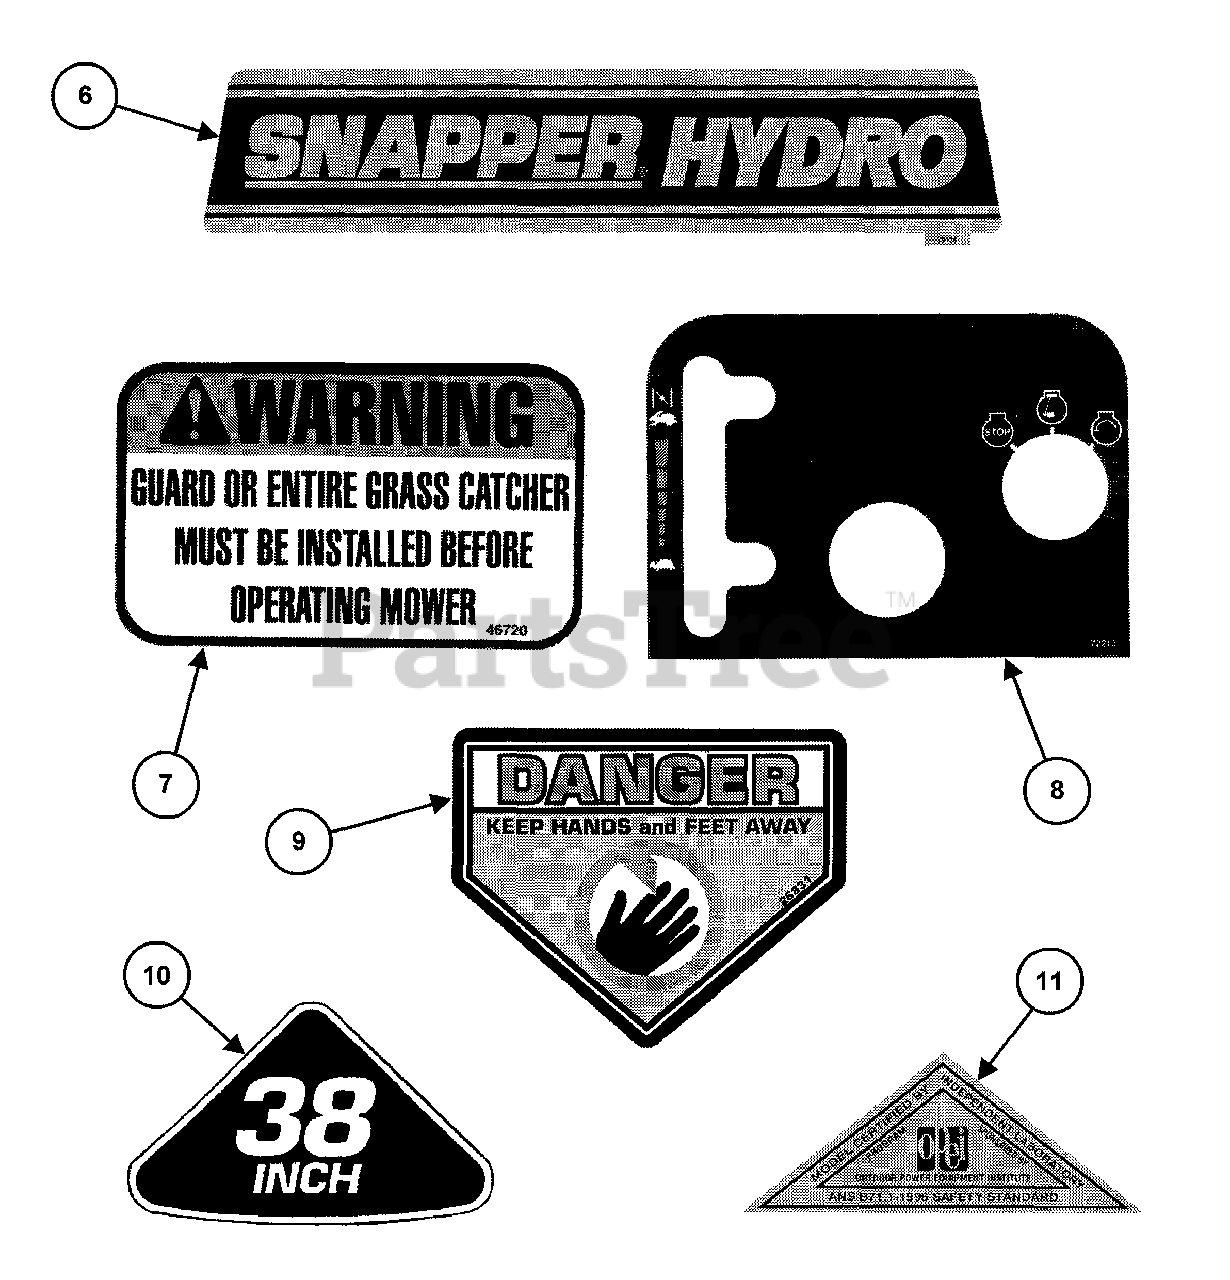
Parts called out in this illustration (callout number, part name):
6	DECAL, Seat Pedestal
7	DECAL, Chute/Deflector
8	DECAL, Throttle Control
9	DECAL, CPSC (Heavy Adhesive)
10	DECAL, 38 Inch Deck
11	DECAL, OPEI (Ride On)
